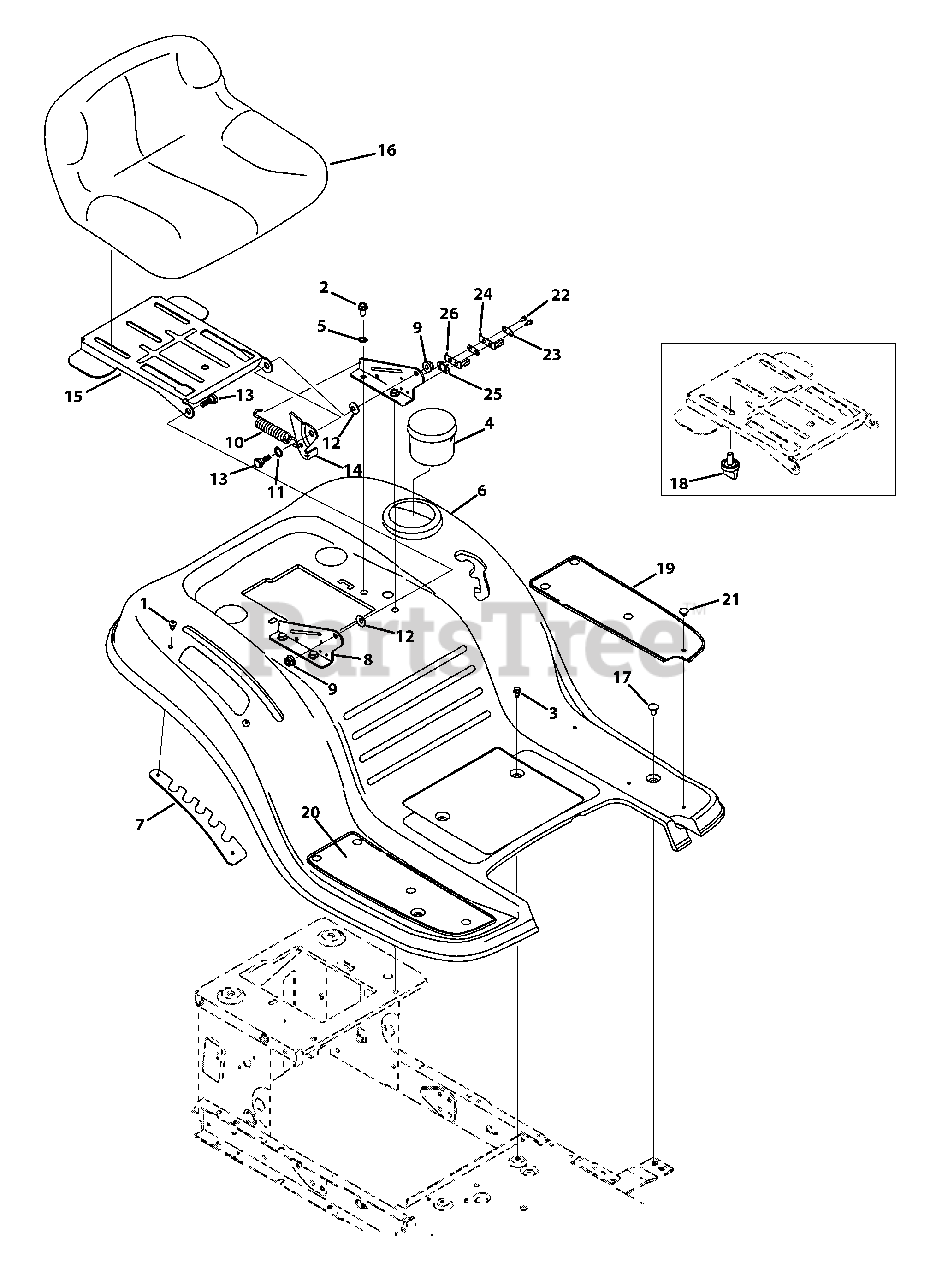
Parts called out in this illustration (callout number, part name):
1	Screw, 1/4-20 x .500
2	Screw, 5/16-18 x .750
3	Screw Pan Torx Head, 1/4-20 x .500
5	Loack Washer, 5/16
6	Fender
7	Lift Adjuster Bracket
8	Seat Mount Bracket
9	Flangelock Nut, 5/16-18
10	Extension Spring
11	Flat Washer, .510x .750 x .033
12	Bell Washer, .340 x .872 x .060
13	Shoulder Screw, 5/16-18 x .437 x .268
14	Lift Seat Bracket
15	Pivot Seat Manual Adjust Bracket
16	Low Back Seat, Black
17	Screw Carriage, 1/4-20 x .62
18	Knob, 3/8-16 x .875
19	Foot Pad, Abrasive, LH
20	Foot Pad, Abrasive, RH
21	Ratchet Clip, .250 x .500
22	Screw, 8-18 x .500
23	Insulator Plate
24	Outer Seat SPring
25	Insulator Boss Plate
26	Inner Seat Spring
